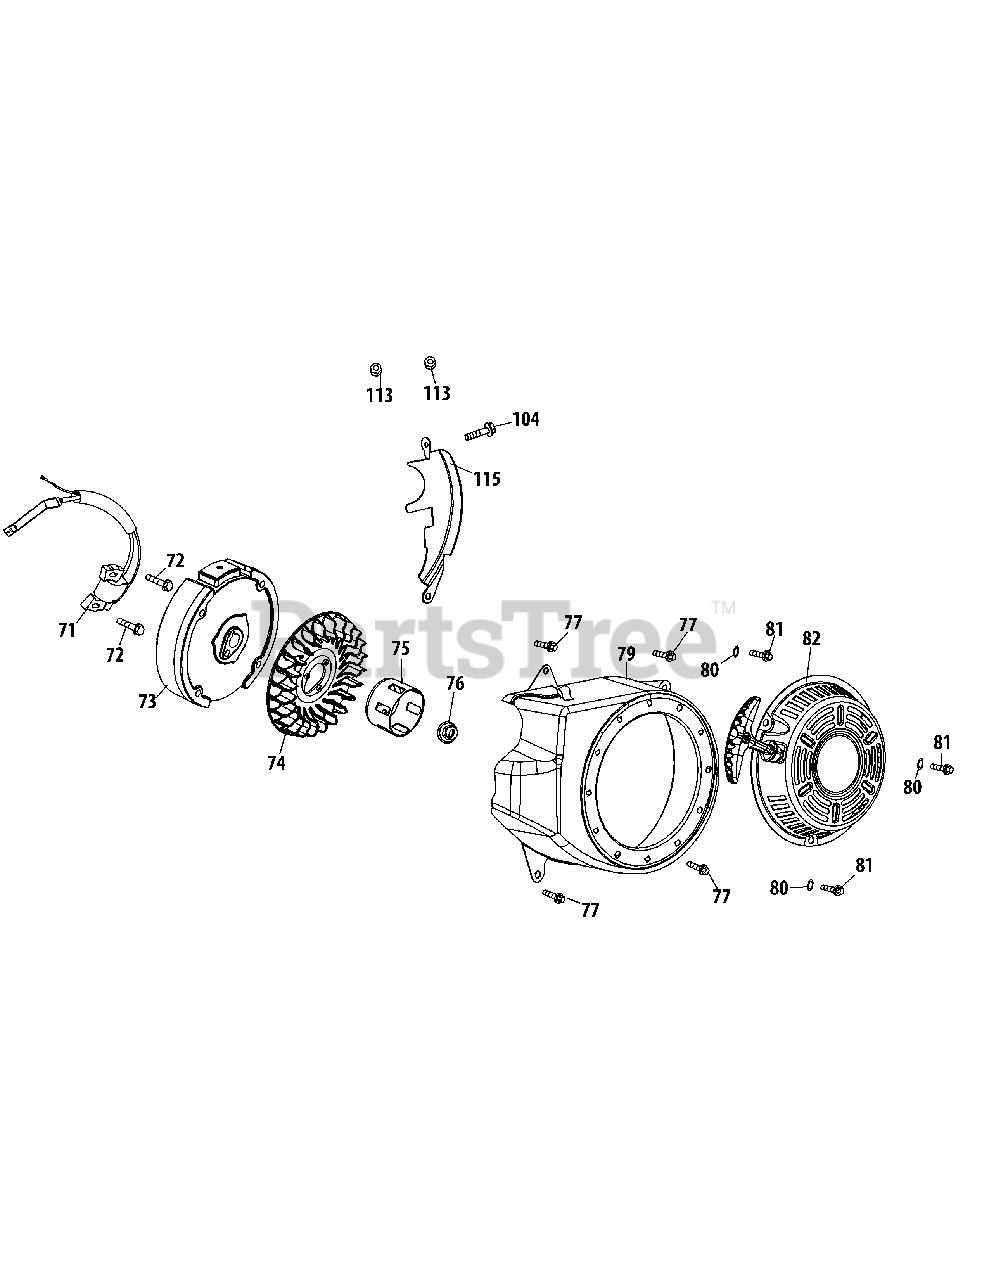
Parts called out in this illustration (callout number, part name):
71	Ignition Coil
72	Flange Bolt M6X25
74	Cooling Fan
75	Starter Cup
76	Nut M14
77	Bolt:M6X12 Zinc
79	Blower Housing
80	Flat Washer
81	Flange Bolt
82	Recoil Starter Assembly
114	Bolt M6×20
115	Blower Housing Shield
